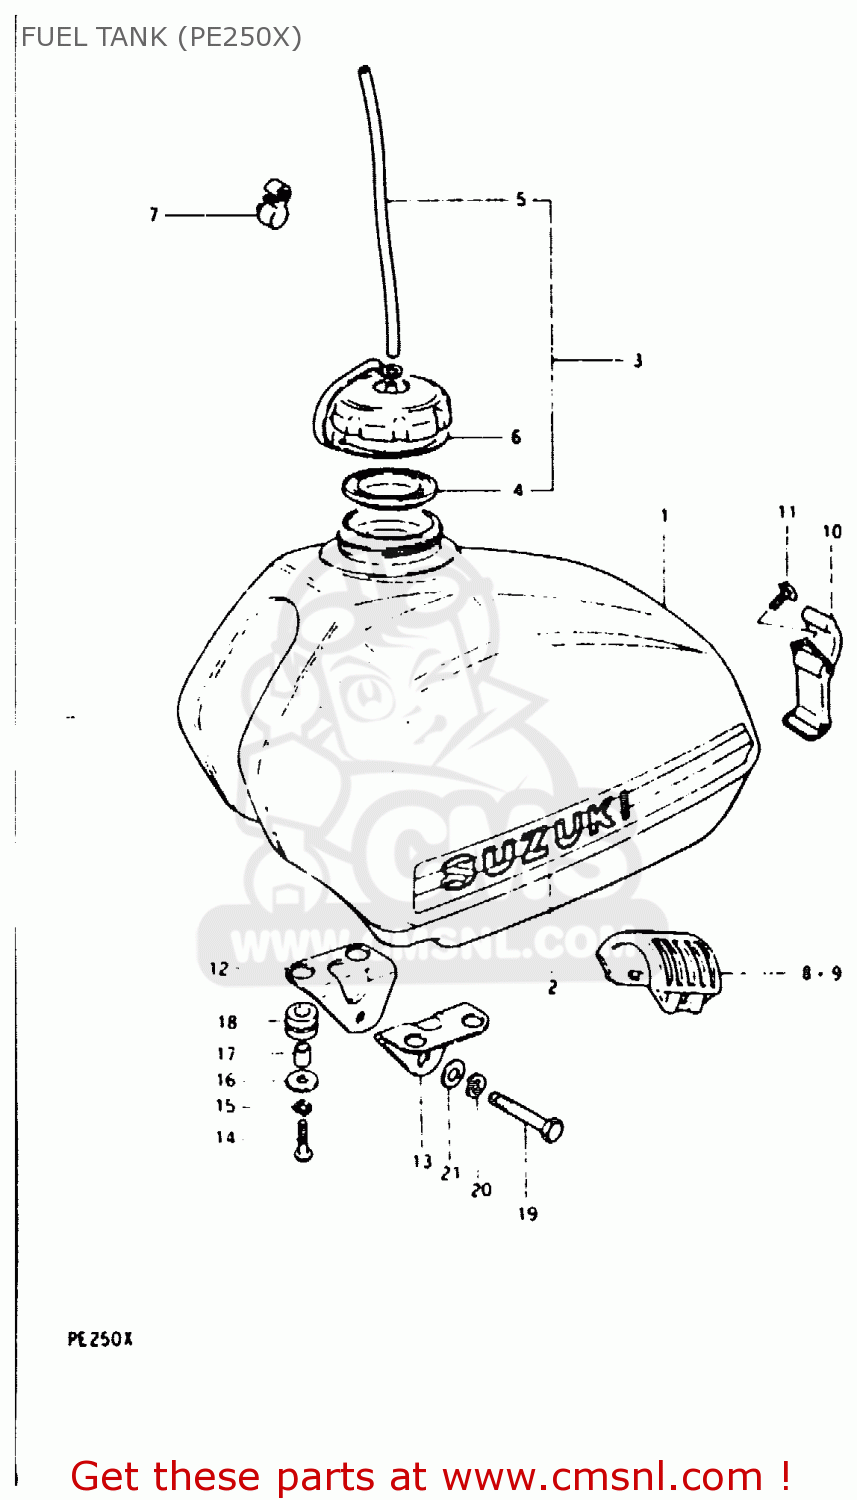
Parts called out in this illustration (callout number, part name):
1	TANK ASSEMBLY,FUEL
2	TAPE SET,FUEL TANK
3	CAP,FUEL TANK
4	GASKET,FUEL TANK CAP (NAS)
5	HOSE
6	BAND,FUEL TANK CAP
7	CLAMP,BREATHER HOSE
8	CUSHION,FUEL TANK
9	CUSHION,FUEL TANK UPR FR
10	BAND
11	SCREW(6X18)
12	BRACKET,FUEL TANK
13	BRACKET,FUEL TANK,LOWER
14	SCREW
15	LOCK WASHER
16	WASHER (6.5*24*1.6)
17	SPACER(6.8X12X11)
18	CUSHION
19	BOLT
20	LOCK WASHER
21	WASHER
